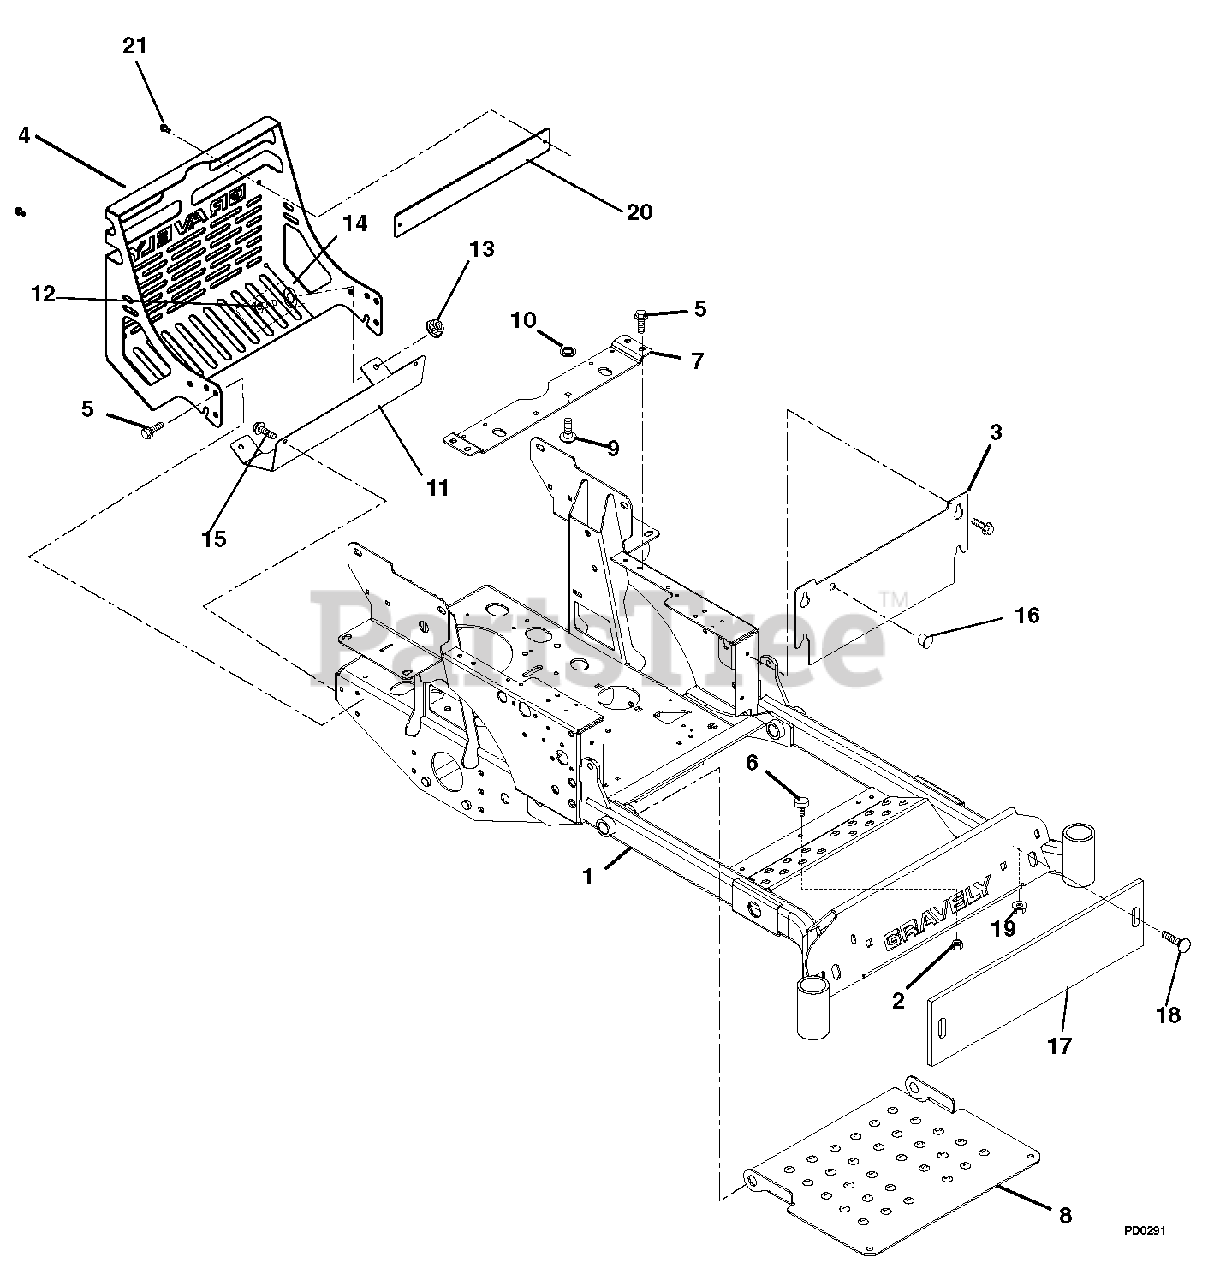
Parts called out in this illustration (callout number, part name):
1	Frame, Compact-Z
2	Nut, Spin Lock Flange .312-18
3	Access Panel
4	Bumper, Rear
5	Screw, Tapping .38-16 x .75 Hex Washer Head
6	Bumper, Rubber
7	Seat Support
8	Panel, Inspection
9	Bolt, Round Head Square Short Neck .31-18 x .75 Grade 5
10	Nut, Push .312
11	Heat Shield, Compact Z
12	Bolt, Hex .38-16 x .75 Grade 5
13	Nut, Nyloc Flange .38-16
14	Washer, Flat Steel .438 x 1.00 x .083
15	Screw, Tapping .38-16 x .50 Hex Washer Head
16	Plug, Hole .56
17	Counterwieght CZ Front- Black
18	Bolt, Round Head Square Neck .50-13 x 2.50 Grade 5
19	Nut .50-13 Nyloc Flange
20	Plate, Bumper
21	Screw, Tapping .25-20 x .50 Hex Washer Head
